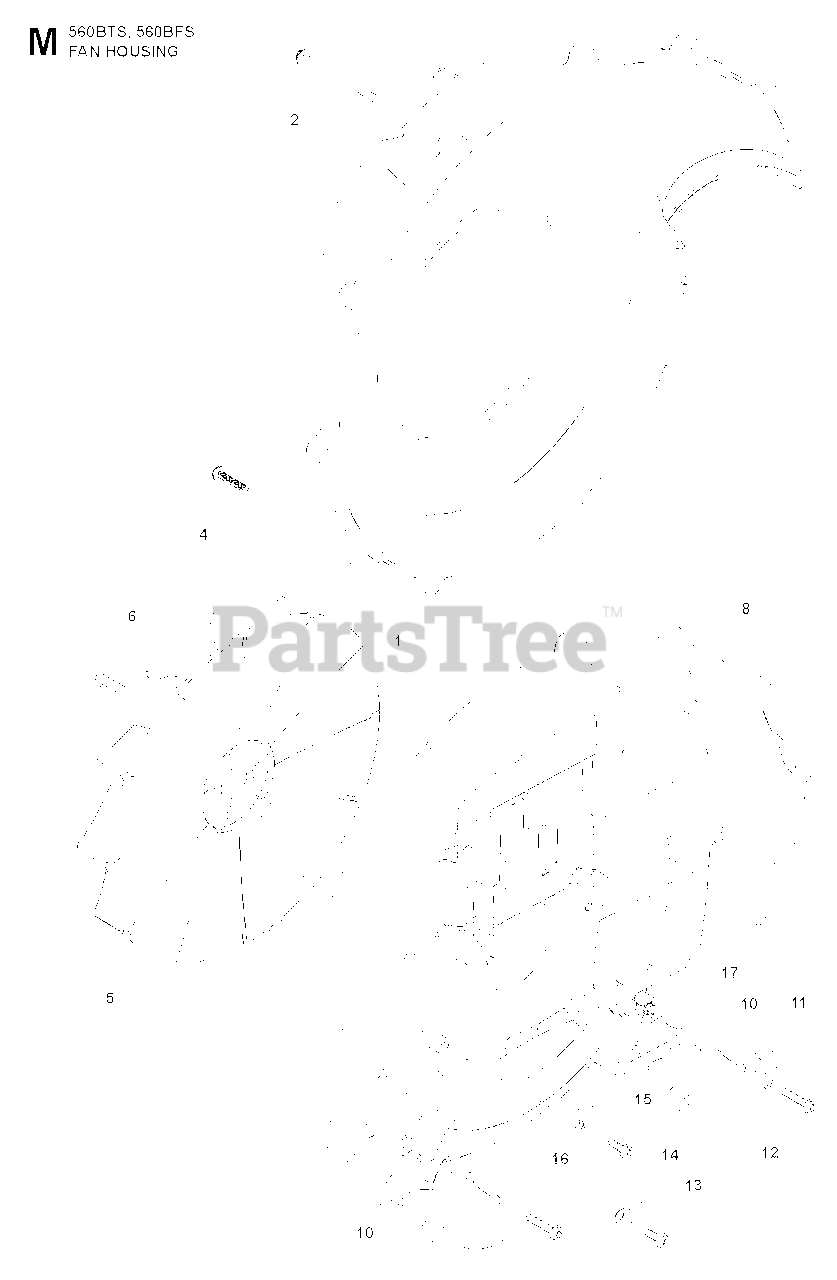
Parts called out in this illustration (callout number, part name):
10	BRACKET DAMPNER
14	CLAMP
16	CLAMP
